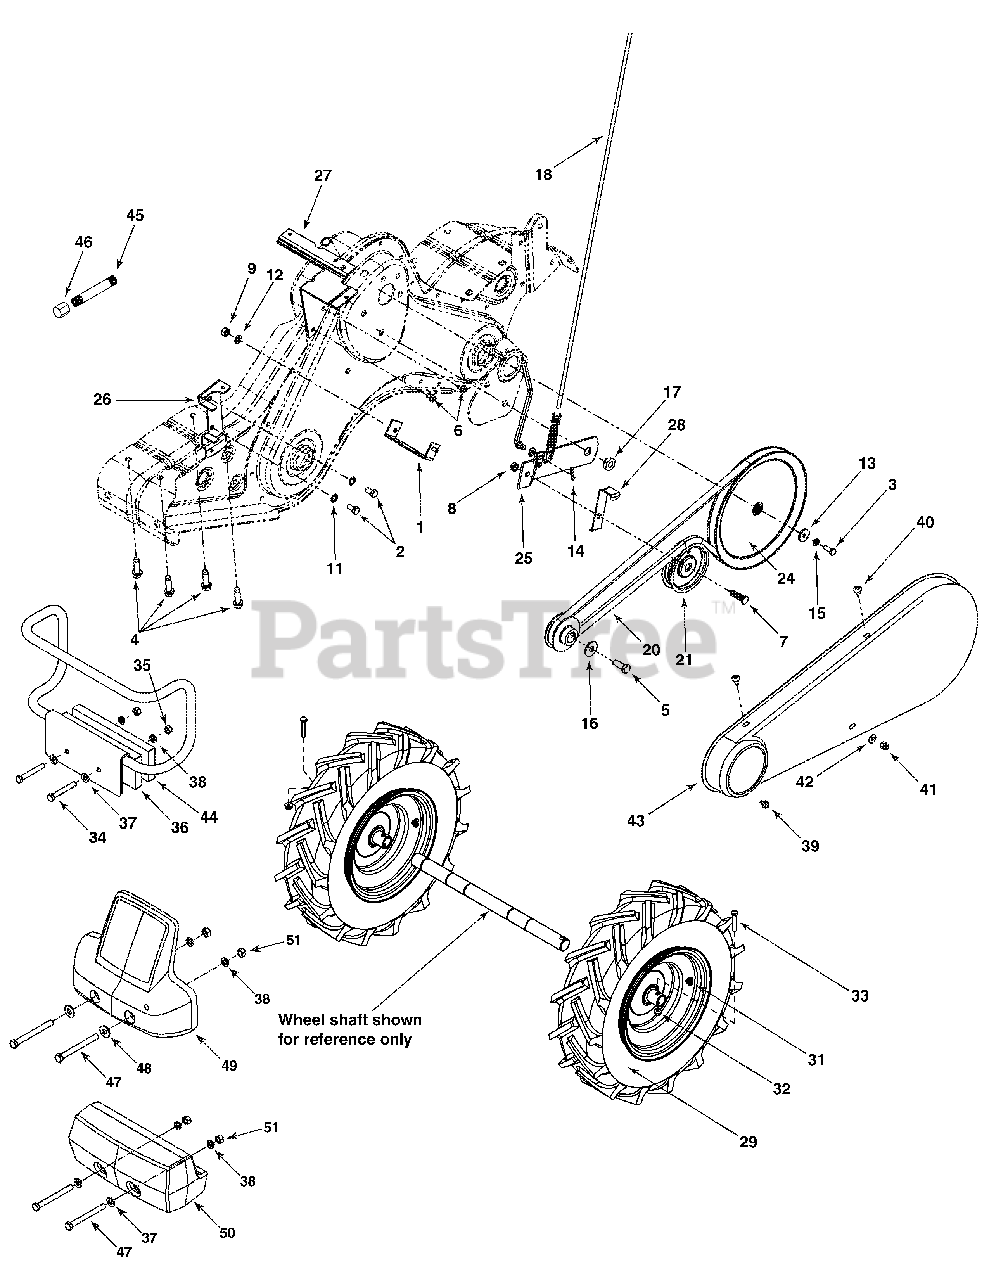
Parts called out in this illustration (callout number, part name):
2	Hex Bolt 5/16-24 x .62"
3	Hex Bolt 1/4-28 x .75"
4	Hex Washer Screw 3/8-16 x 1.25"
5	Hex Bolt 3/8-24 x 1.0
6	Hex Washer Screw
7	Hex Cap Screw 3/8-16 x 1.25
8	Lock Jam Nut 3/8-16
9	Hex Nut 5/16-18
10	Internal Cotter Pin
11	Hairpin Clip
12	Lock Washer 5/16"
13	Flat Washer .25 ID x .93 OD
14	Spring Washer .317 ID x .625 OD
15	Lock Washer 1/4" ID
16	Bell Washer .396 ID x 1.14 OD
17	Shoulder Nut 7/16-20
18	Clutch Cable
19	Idler Pulley Rod
20	V-Belt
21	Flat Idler w/Flange 3.75 OD
22	Outer Engine Pulley Half
23	Inner Engine Pulley Half
24	Input Pulley
25	Idler Bracket
29	Wheel Assembly 16.0 x 4.6 x 8
31	Air Valve
32	Hex Head Screw 1/4-20
33	Flange Lock Nut 1/4-20
34	Hex Bolt 1/2-20 x 3.50
35	Hex Nut 1/2-20
38	Lock Washer 1/2
39	Hex Screw 1/4-20 x .375
40	Screw 1/4-14 x .625
41	Lock Nut
42	Flat Washer .271 ID x .630 OD
44	Bell Washer .340 ID x .872 OD
45	Straight Pipe 1/4-3.5"
46	End Cap
47	Hex Head Screw, 1/2-13 x 5.00
48	Flat Washer 1/2 x 1.25 x .10
49	Counterweight
50	Counterweight
51	Hex Nut, 1/2-13
